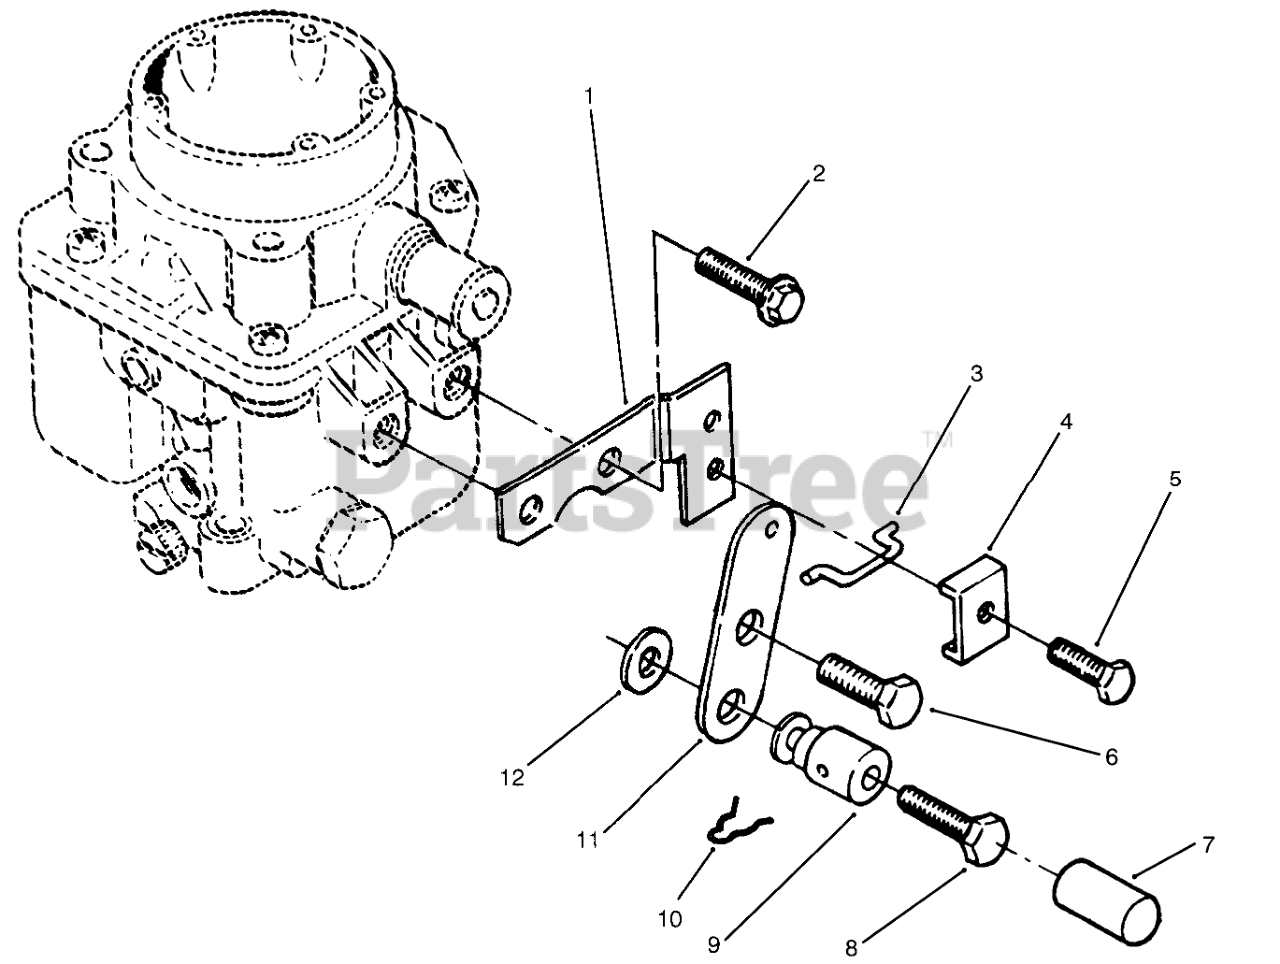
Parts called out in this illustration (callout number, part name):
1	BRACKET
2	SCREW-HWH
3	LINK-CHOKE
5	SCREW-TAPPING
6	MACHINE SCREW
8	SCREW
9	SWIVEL-CHOKE LEVER
10	PIN-COTTER
11	CHOKE-LEVER (PRIMED)
12	Washer
